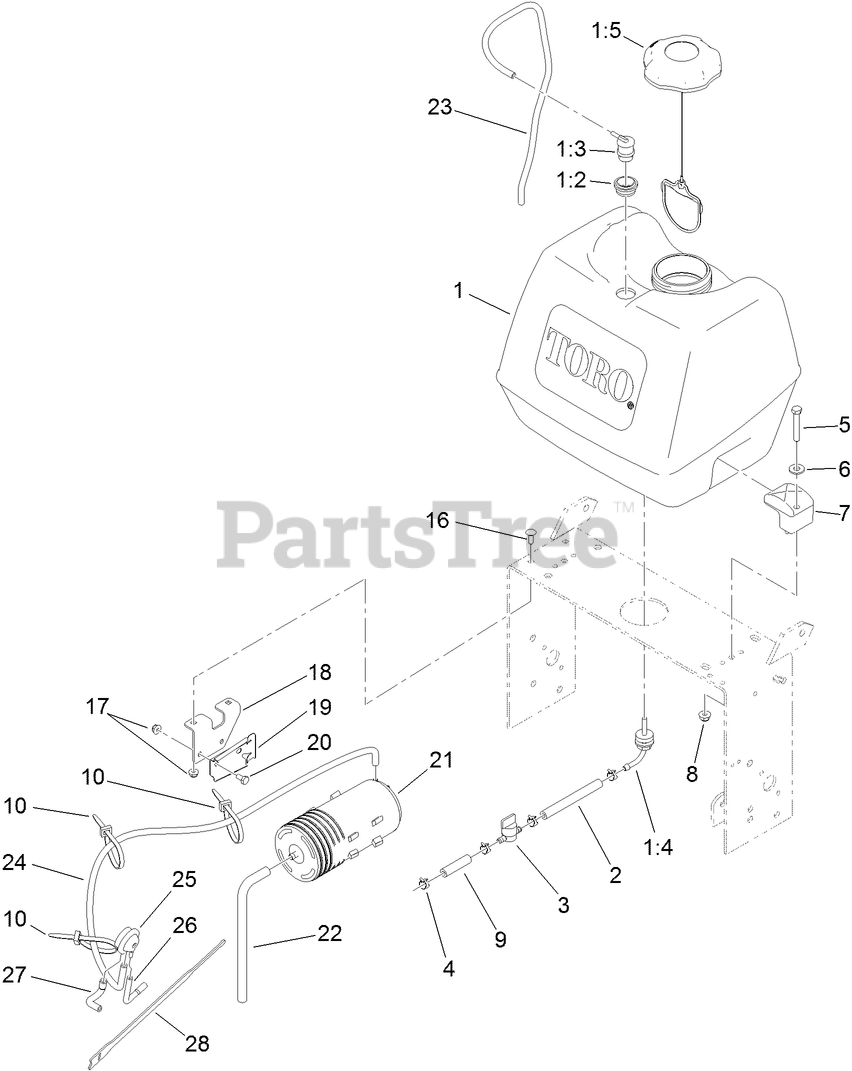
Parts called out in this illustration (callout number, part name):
1	FUEL TANK ASM
1:2	GROMMET
1:3	VALVE-VENT, FUEL
1:4	FITTING-FUEL, BULKHEAD
1:5	CAP-FUEL, RATCHETING
2	HOSE-FUEL
3	VALVE-FUEL
4	CLAMP-HOSE
5	SCREW-HH
6	WASHER-FLAT
8	NUT-HF, NI
9	HOSE-FUEL
10	TIE-CABLE
16	BOLT-CARR
17	NUT-HF
18	BRACKET-CANISTER, CARBON
19	BRACKET-CANISTER, CARBON
20	SCREW-HH
21	CANISTER-CARBON, 800CC
22	HOSE-VENT, CANISTER
23	HOSE-VENT
24	HOSE-VENT, FORMED
25	VALVE-CONTROL, VACUUM
26	HOSE-VENT, FORMED
27	HOSE-VENT, FORMED
28	STRAP-VELCRO, CABLE TIE
